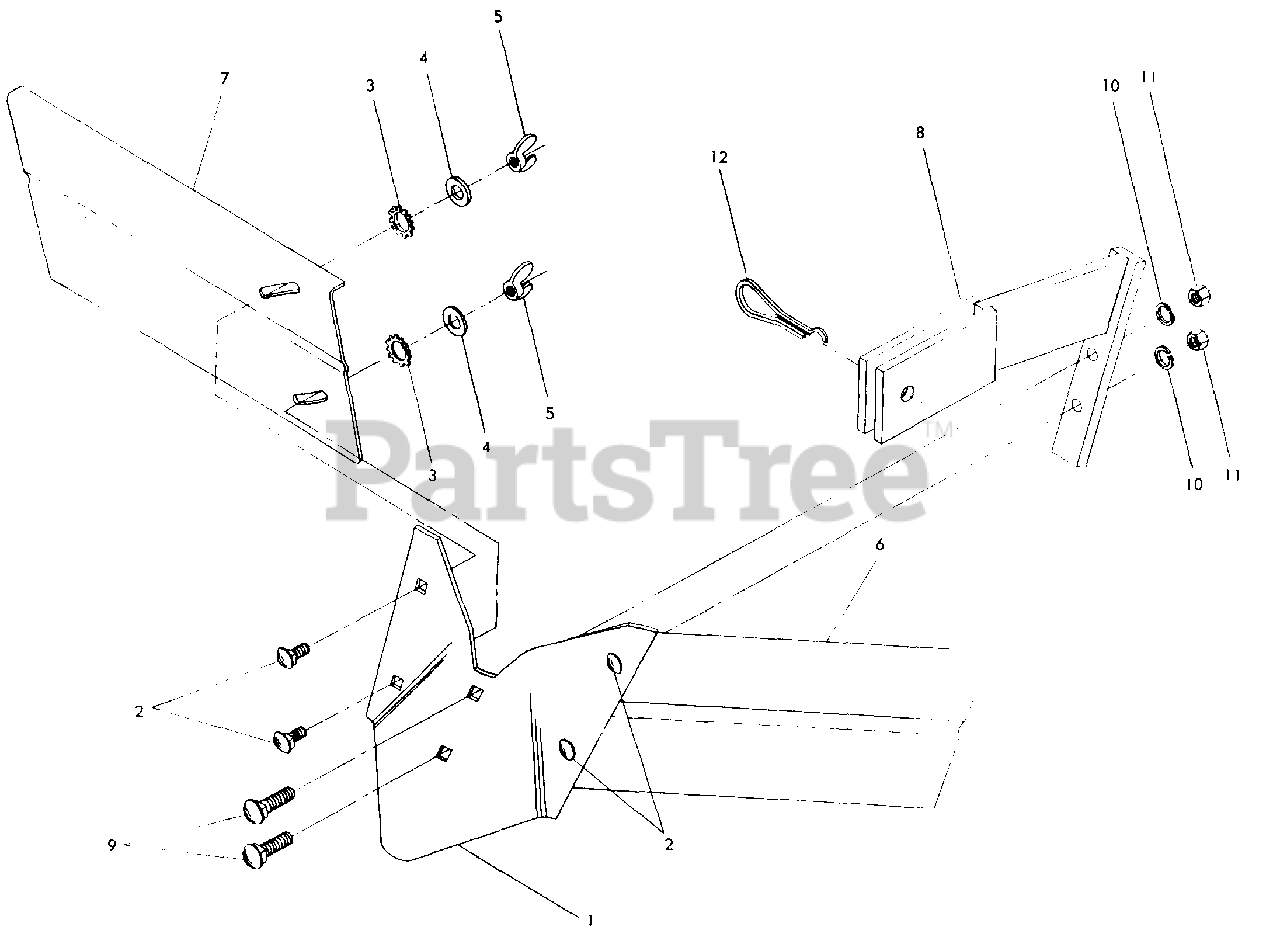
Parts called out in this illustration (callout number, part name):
1	Furrower-blade only
2	Carriage Bolt-5/16-18 x 3/4"
3	Star Washer-ext. tooth, 5/16"
4	Washer-plain, 5/16" S.A.E
5	Wing Nut-5/16"-18
6	Hiller Wing-left
7	Hiller Wing-right
8	Bracket-blade mounting
9	Carriage Bolt-blade mounting, 3/8-16 x 1-1/2"
10	Lockwasher - spring lock, 3/8" plated
11	Nut-hex, 3/8"-16, plated
12	Pin-clinch
